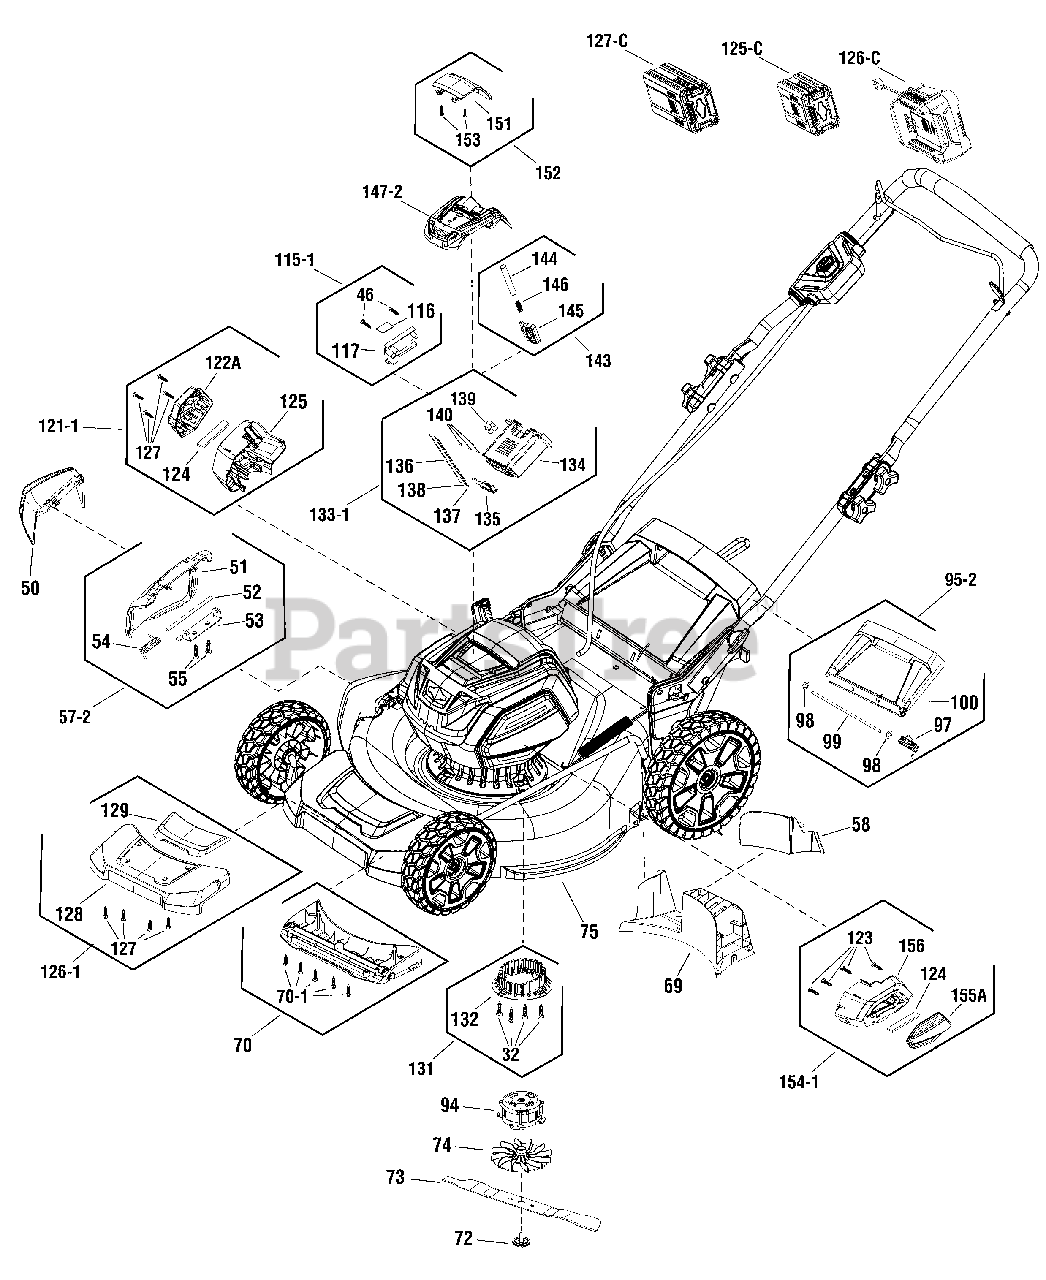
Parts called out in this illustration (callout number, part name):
32	SCREW
46	SCREW
50	KIT, DEFLECTOR
51	COVER
52	SHAFT
53	BRACKET
54	SPRING
55	BOLT
57-2	KIT, COVER, EU
58	KIT, PLUG
69	KIT, BACK BULKHEAD
70	KIT, FRONT BULKHEAD
70-1	SCREW
72	KIT, BOLT
73	KIT, BLADE
74	KIT, FAN
75	KIT, DECK
94	KIT, MOTOR
95-2	KIT, REAR COVER ASSEMBLY, EU
97	SPRING
98	COTTER PIN
99	SHAFT
100	REAR COVER
115-1	KIT, PCB, EU&AU
116	SENSOR
117	PCB
121-1	KIT, RIGHT COVER
122A	RIGHT SIDE COVER
123	SCREW
124	DUST SCREEN
125	RIGHT HOUSING
125-C	BATTERY, 2AH, EU
126-1	KIT, FRONT PANEL
126-C	CHARGER, RAPID, EU
127	SCREW
127-C	BATTERY, 4AH, EU
128	BUMPER
129	BUMPER COVER
131	KIT, BASE
132	BASE
133-1	KIT, BATTERY COMPARTMENT ASSEMBLY, AU
134	BATTERY HOUSING
135	INSERT
136	WIRE
137	WIRE
138	WIRE
139	COVER
140	CONTACT
143	KIT, BATTERY RELEASE
144	PIN
145	BATTERY RELEASE BUTTON
146	SPRING
147-2	KIT, TOP COVER, EU
151	RAIN CAP
152	KIT, BATTERY COVER
153	SCREW
154-1	KIT, LEFT COVER
155A	LEFT SIDE COVER
156	LEFT DECORATIVE COVER
